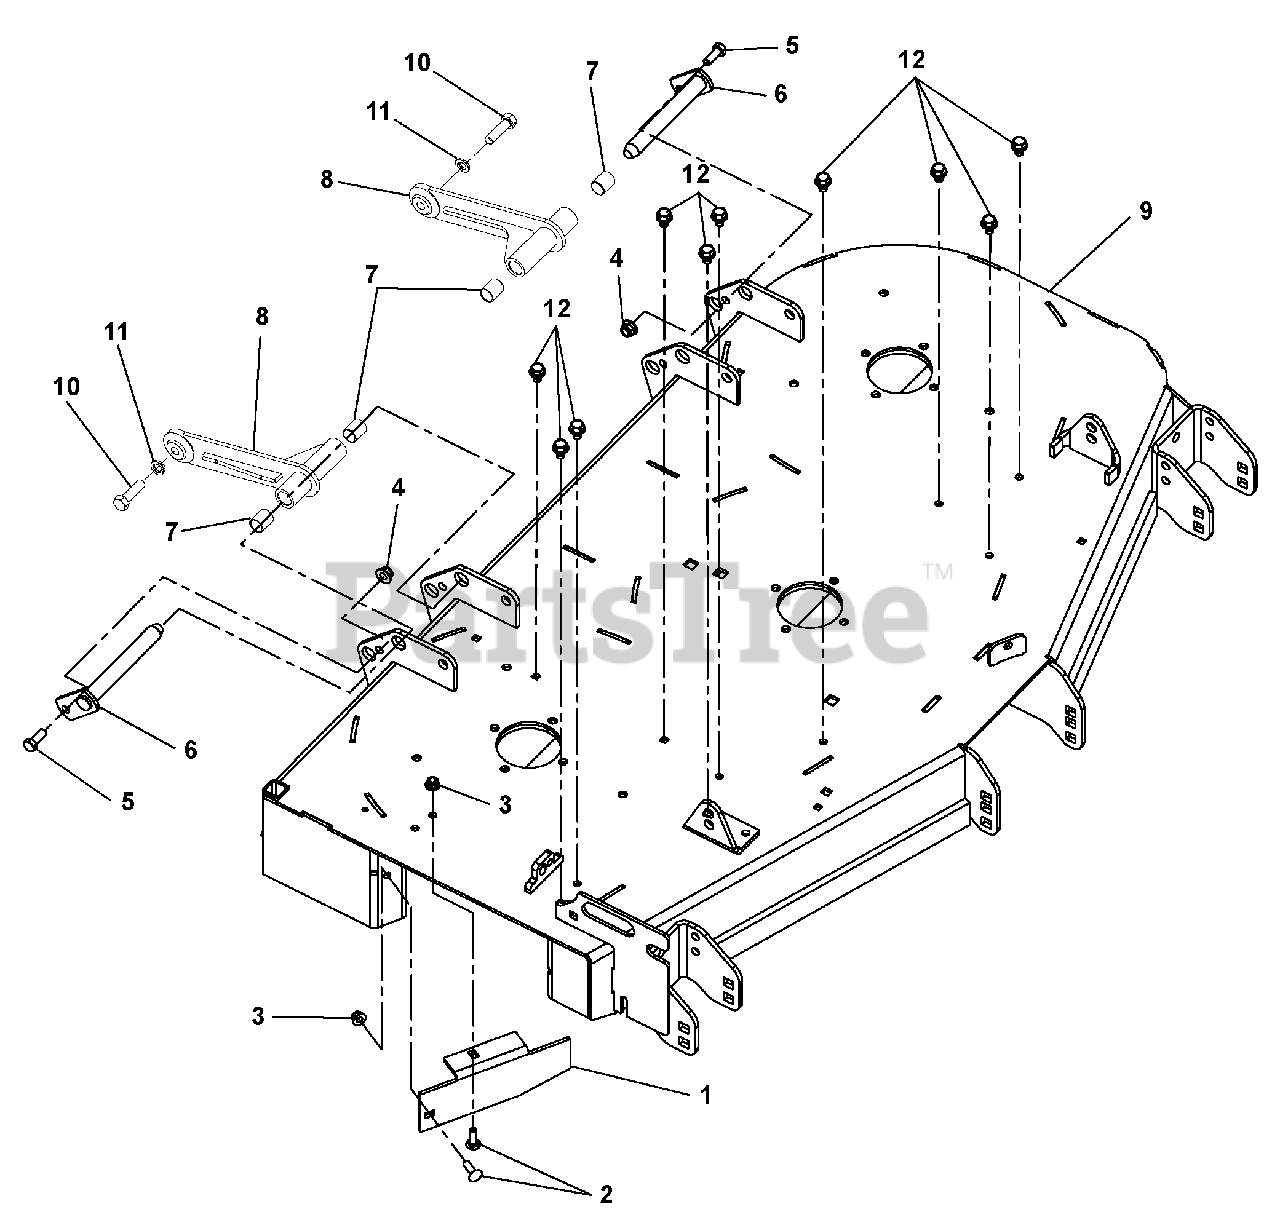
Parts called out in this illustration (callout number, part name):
1	44" - 48" Rear Discharge Baffle (060)
2	Bolt, Round Head Square Neck .31-18 x 1.00 Grade 5
3	Nut, .31-18 Nyloc Flange
4	Nut, .38-16 Nyloc Flange
5	Bolt, Hex .38-16 x 1.00 Grade 5
6	Weldment, Mower Mounting Pin
7	Bearing, .75 x .875 x 1.00
8	Deck Pusher Arm Weldment
9	48" 100I Side Discharge Deck (060)
10	Bolt, Hex .50-13 x 1.75 Grade 5
11	Washer, Locking .50 x .125 Regular
12	Screw, Tapping .38-16 x .50 Hex Washer Head
